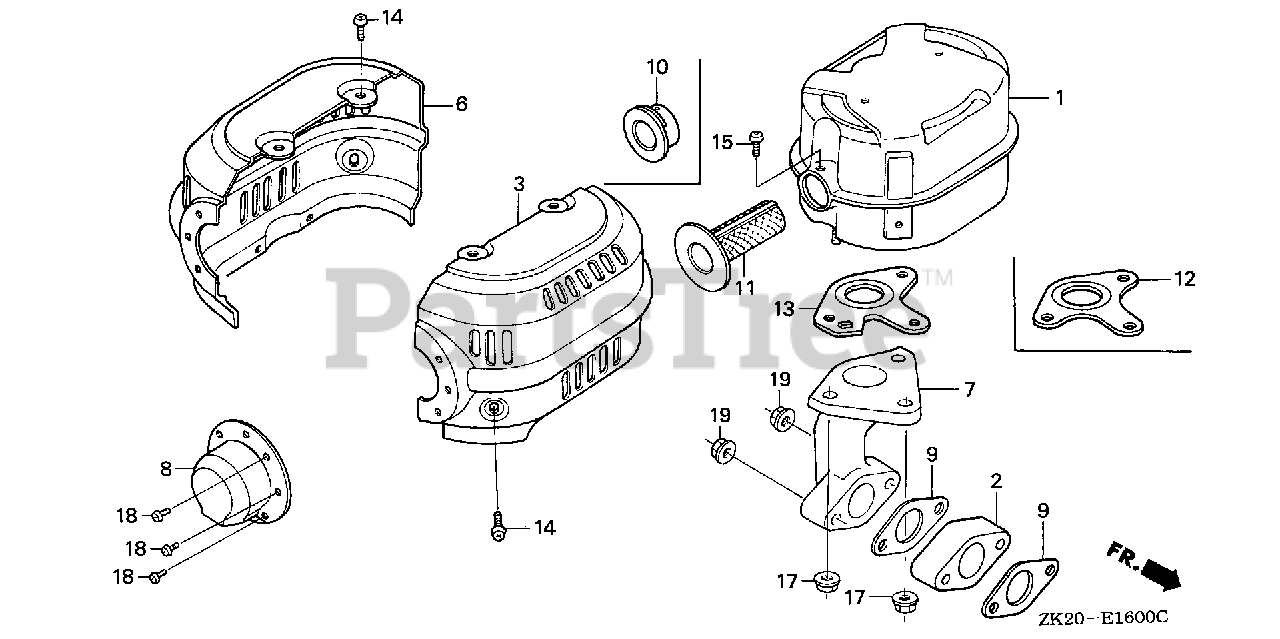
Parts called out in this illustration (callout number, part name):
1	MUFFLER (SILENT)
3	PROTECTOR, R. MUFFLER (STD)
6	PROTECTOR, L. MUFFLER (STD)
8	CAP, MUFFLER
9	GASKET, EX. PIPE
11	ARRESTER, SPARK
13	GASKET, MUFFLER (ARRESTER) (NIPPON LEAKLESS)
14	SCREW, TAPPING (5X8)
15	SCREW, TAPPING (5X8)
17	NUT, FLANGE (8MM)
18	SCREW, TAPPING (4X6)
19	NUT, FLANGE (8MM)
